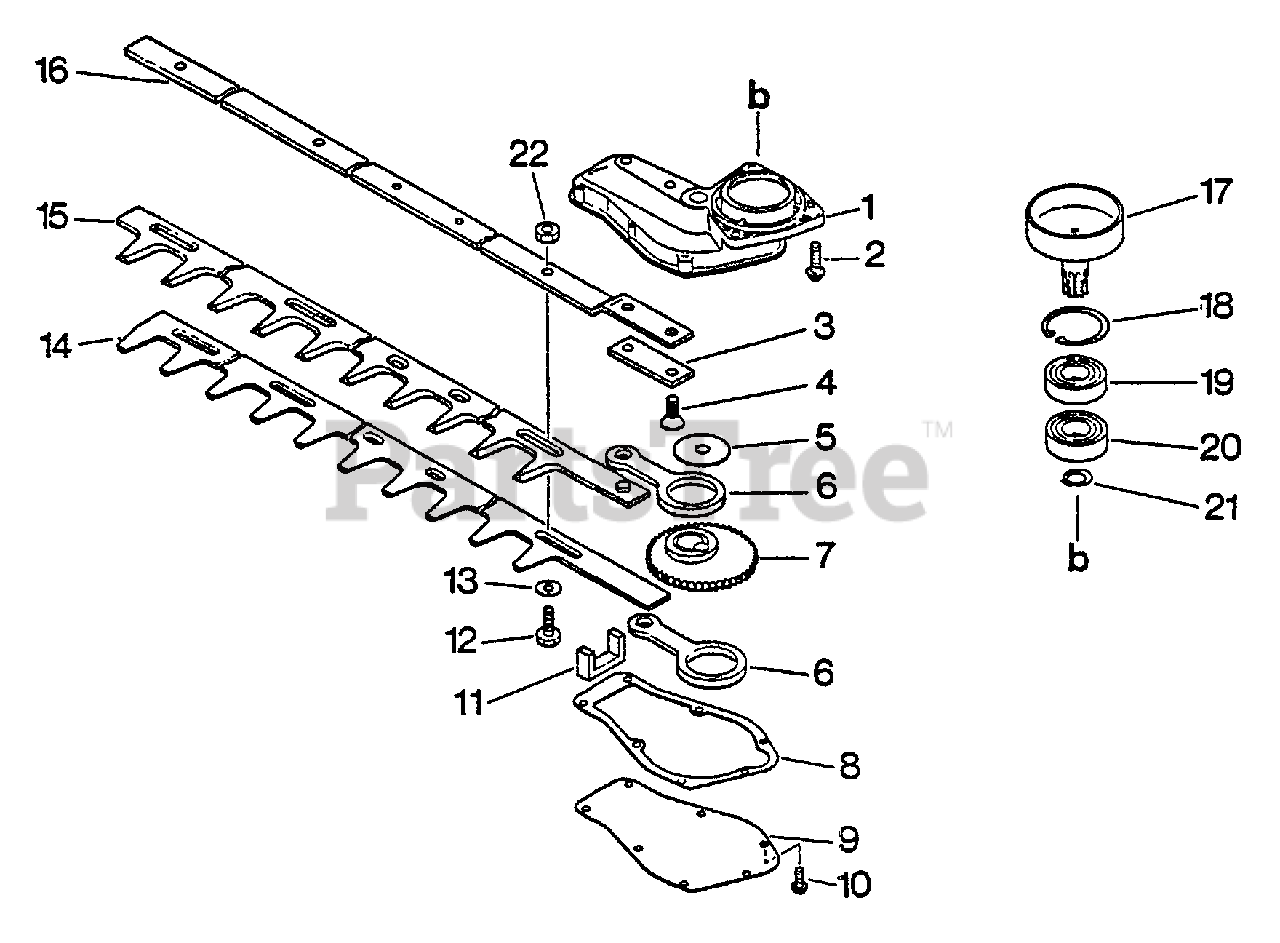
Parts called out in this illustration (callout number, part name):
1	CASE, GEAR
2	SCREW - 5X20
4	SCREW - 6X18
6	ROD, CONNECTING
7	GEAR - DRIVE
8	GASKET, GEAR CASE
9	LID, GEAR CASE
10	SCREW - 4X10
11	SEAL, FELT
13	WASHER - 6
14	BLADE - LOWER
15	BLADE - UPPER
16	SUPPORT, BLADE
17	DRUM, CLUTCH
18	RING, RETAINING - 35
19	BEARING, BALL - 6202
20	BEARING, BALL - 6202
21	RING, RETAINING - 14
22	LOCKNUT - 6
